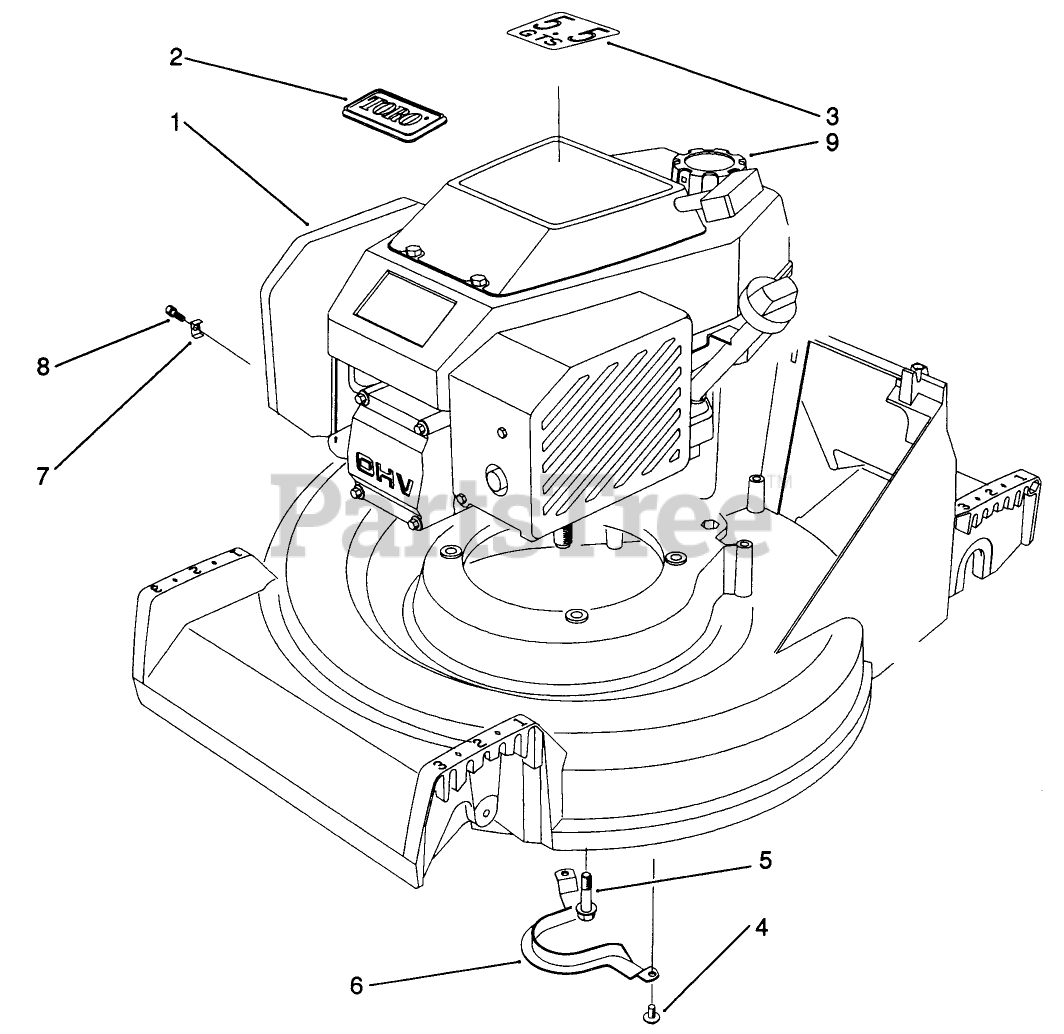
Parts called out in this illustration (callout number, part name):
1	Engine (Incl. Ref. #2 & 3)
2	TORO LOGO PLATE
3	DECAL - ENGINE
4	SCREW-HWHTF
5	SCREW-HWH
6	Guide-Belt
7	CLAMP-CASING
8	Screw
9	GAS CAP ASM
